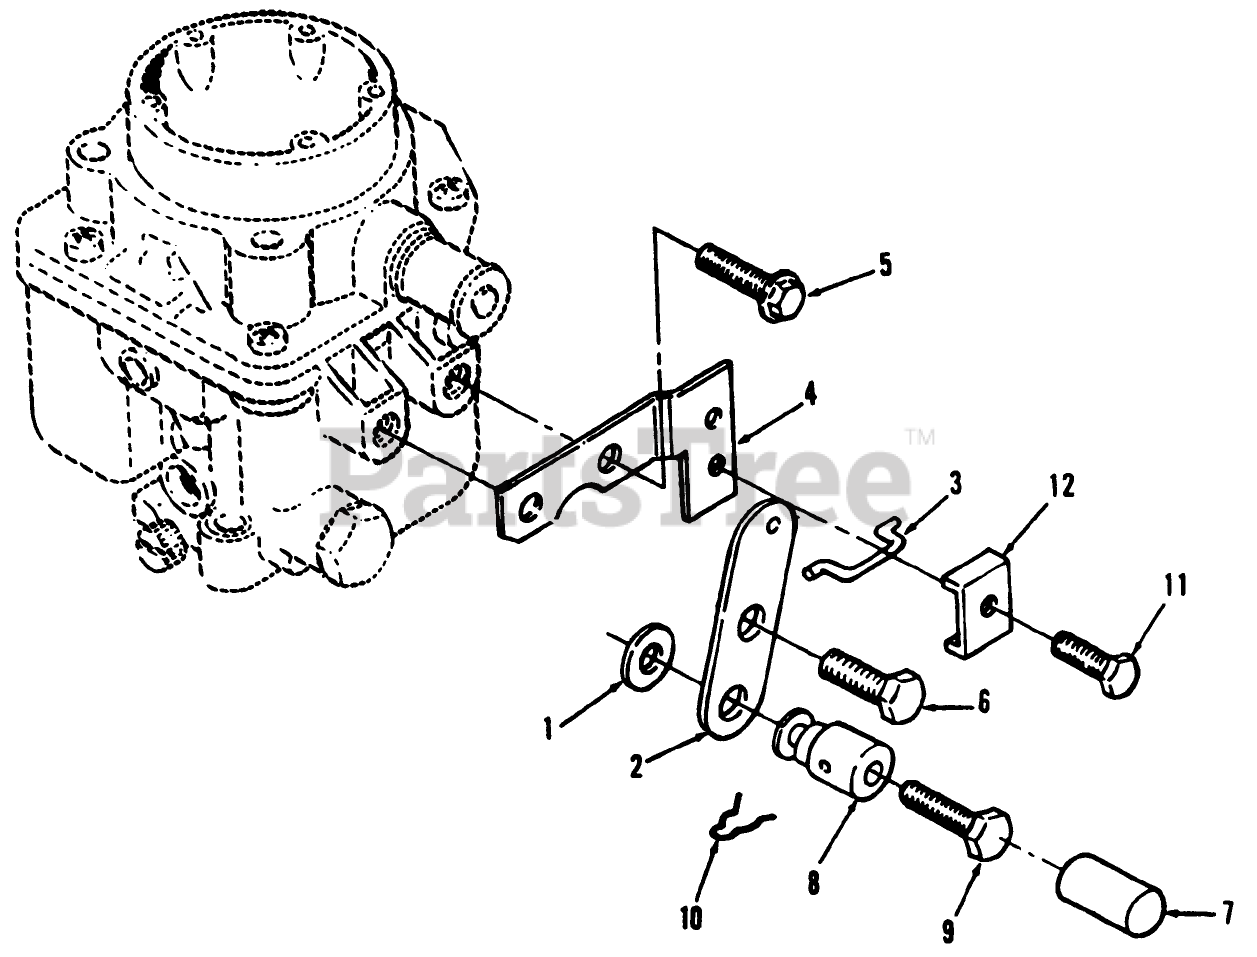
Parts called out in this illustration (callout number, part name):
6	MACHINE SCREW
10	PIN-COTTER
11	SCREW-TAPPING
